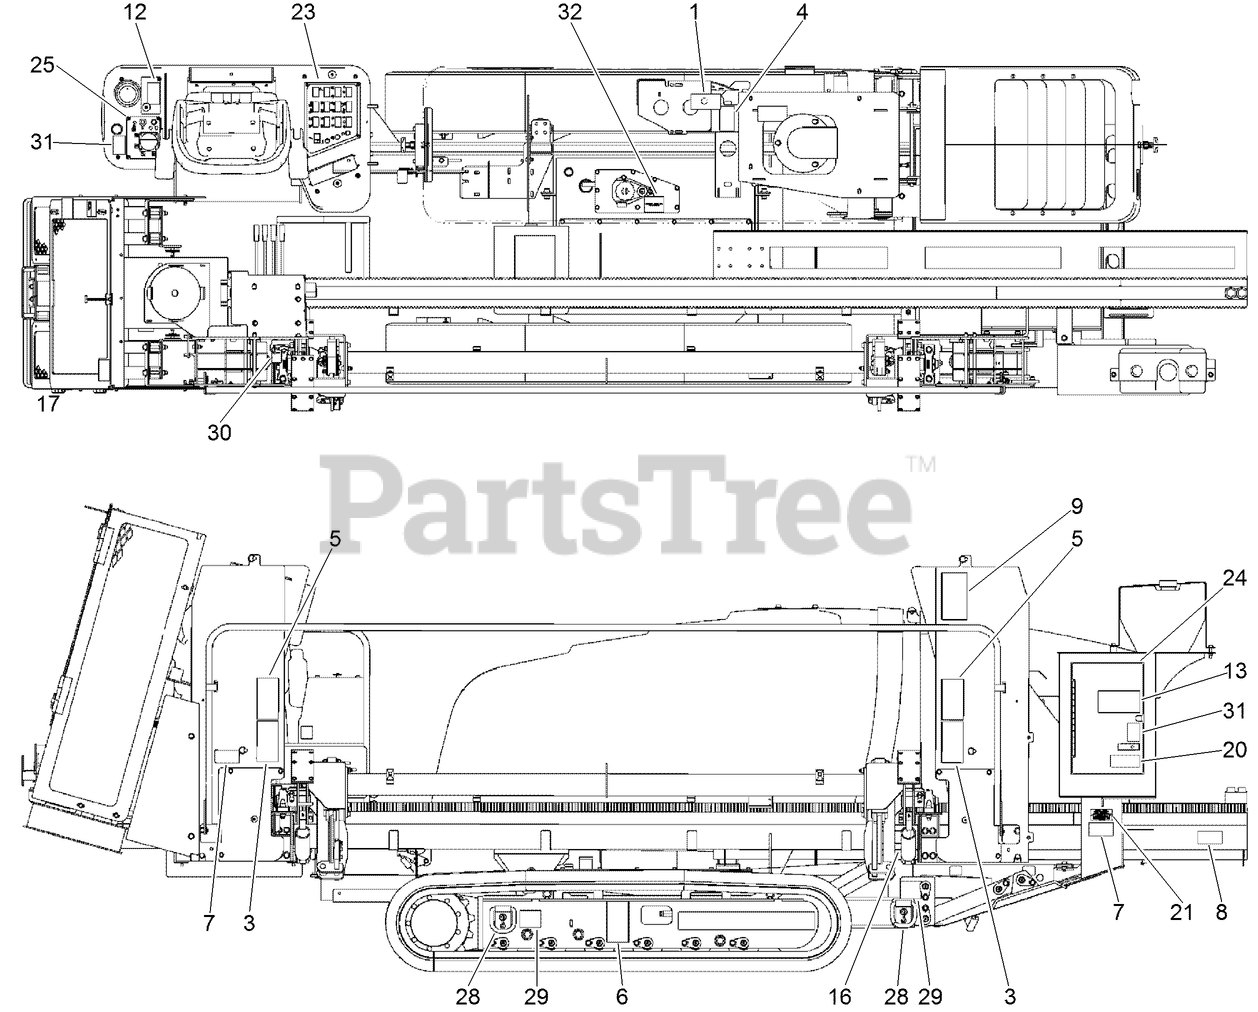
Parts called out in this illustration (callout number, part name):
1	DECAL-Hot Surface
3	DECAL - Danger, Crush, Hands and Feet, ISO
4	DECAL-Battery Explosion
5	DECAL - Warning, Stand Clear, ISO
6	DECAL - Warning, Flying Objects, ISO
7	DECAL - Danger, Hydraulic Components Under Pressure, ISO
8	DECAL - Danger, Crush From Above, ISO
9	DECAL - Danger, Strike Alert Electrocution Hazard, ISO
12	DECAL-Warning, Hearing Protection Required
13	DECAL - Warning, No Riders While Tramming, ISO
16	DECAL - Warning, Use Cylinder Lock For Service, ISO
17	DECAL - Danger, Entanglement Hazard, Small, ISO
20	DECAL - Warning, Read Operators Manual, ISO
21	PLATE - Serial Number
24	OVERLAY - Rear Controls
25	DECAL - Joystick Overlay
28	DECAL - Lift Hook Location
29	DECAL-Tie Down
30	DECAL - Row Selector
31	DECAL - Call Before You Dig, ISO
32	DECAL - Hydraulic Fluid.
